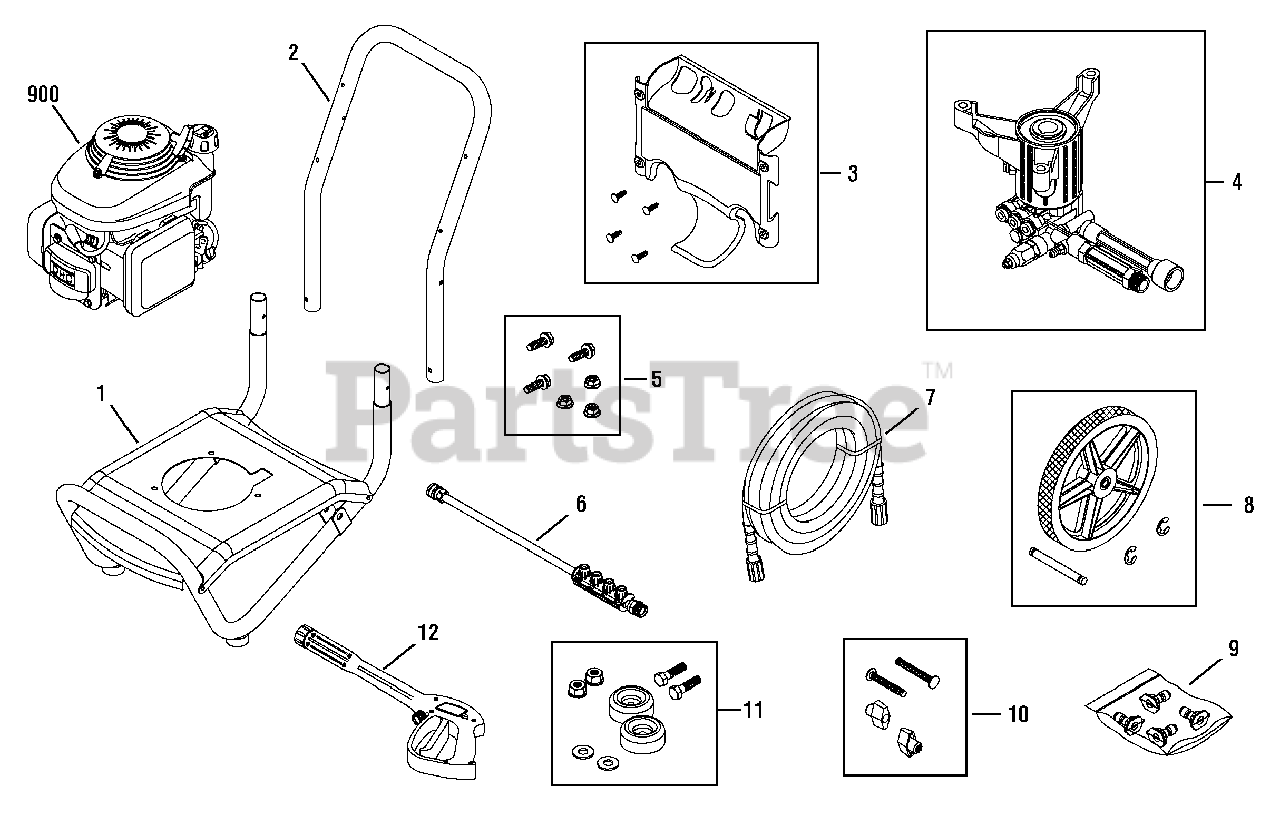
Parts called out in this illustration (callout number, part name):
4	PUMP
5	KIT, Hardware Pump Mounting
6	EXTENSION, QC
7	HOSE
9	KIT, QC Nozzles
10	KIT, Hardware Handle
11	MOUNT, Vibration
12	GUN
900	*ENGINE
